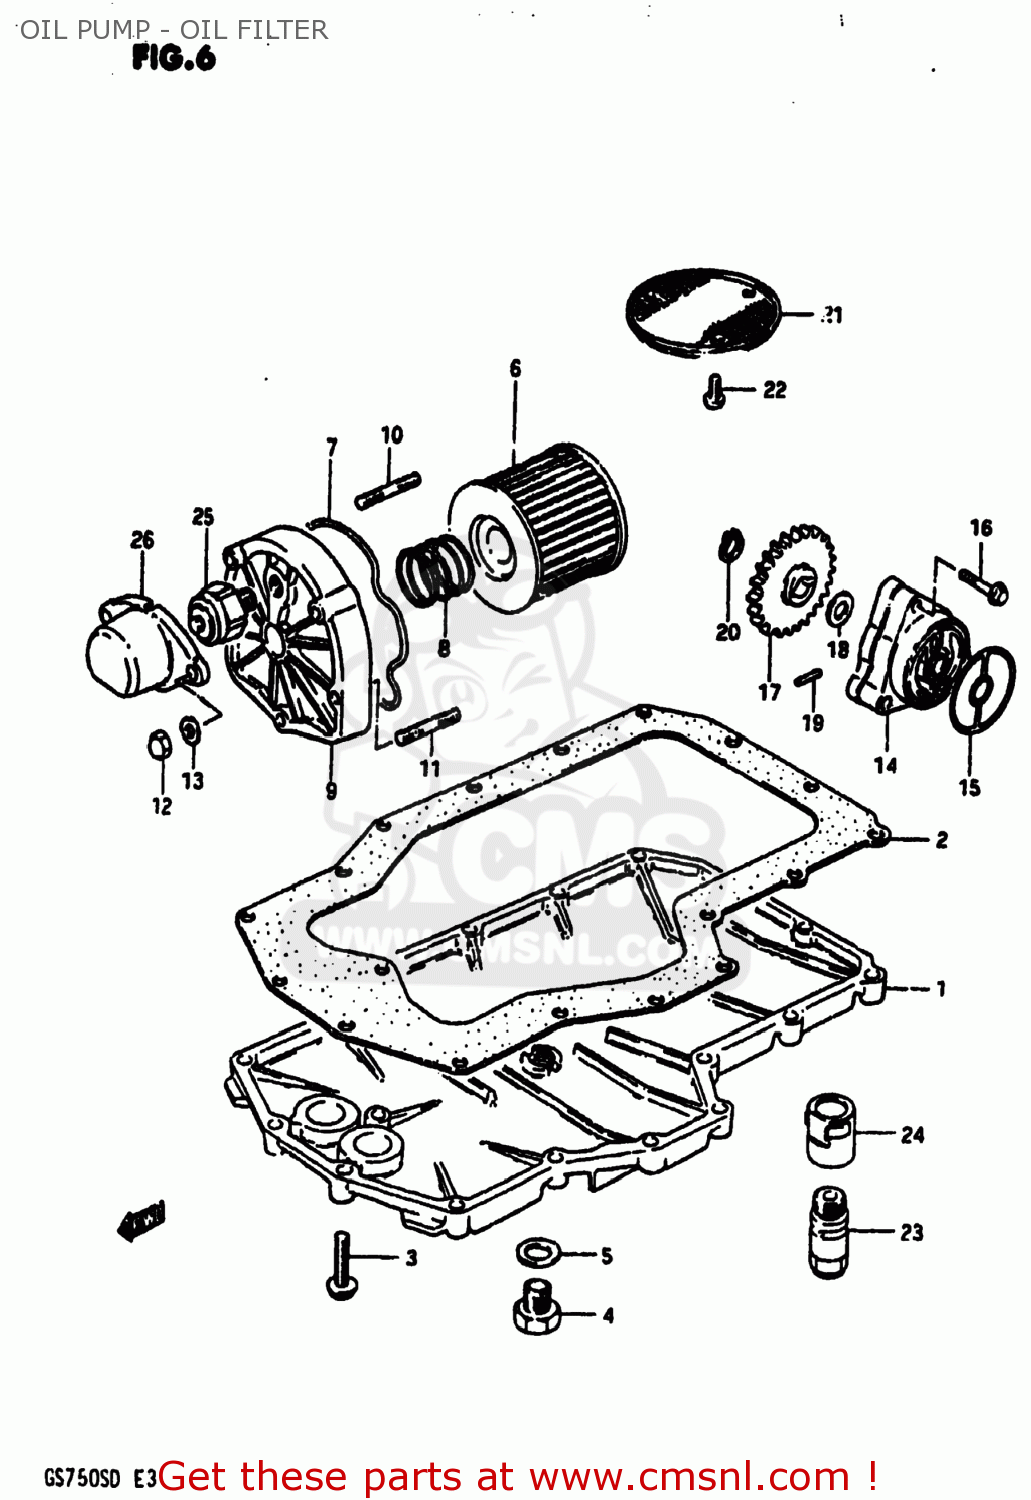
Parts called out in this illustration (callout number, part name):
1	PAN,OIL
2	GASKET,OIL PAN (MCA)
3	BOLT
4	PLUG
5	GASKET(14X19.2X2) (NAS)
6	FILTER ASSY,ENGINE OIL
7	O RING,OIL FILTER CHAMBER CAP
8	SPRING
9	CAP,ENGINE OIL FILTER
10	STUD 6X30
11	STUD 6X25
12	NUT 6MM
13	WASHER
14	PUMP ASSY,ENGINE OIL
15	O-RING,OIL PUMP
16	BOLT(6X32)
17	GEAR,ENG OIL PUMP DRIVEN
18	SHIM
19	PIN(4X15.8)
20	CIRCLIP
21	STRAINER,ENGINE OIL
22	SCREW 6X12
23	VALVE ASSEMBLY,OIL RELIEF
24	GUIDE, OIL REGULATOR
25	SWITCH ASSEMBLY
26	COVER,OIL PRESSURE SWITCH
